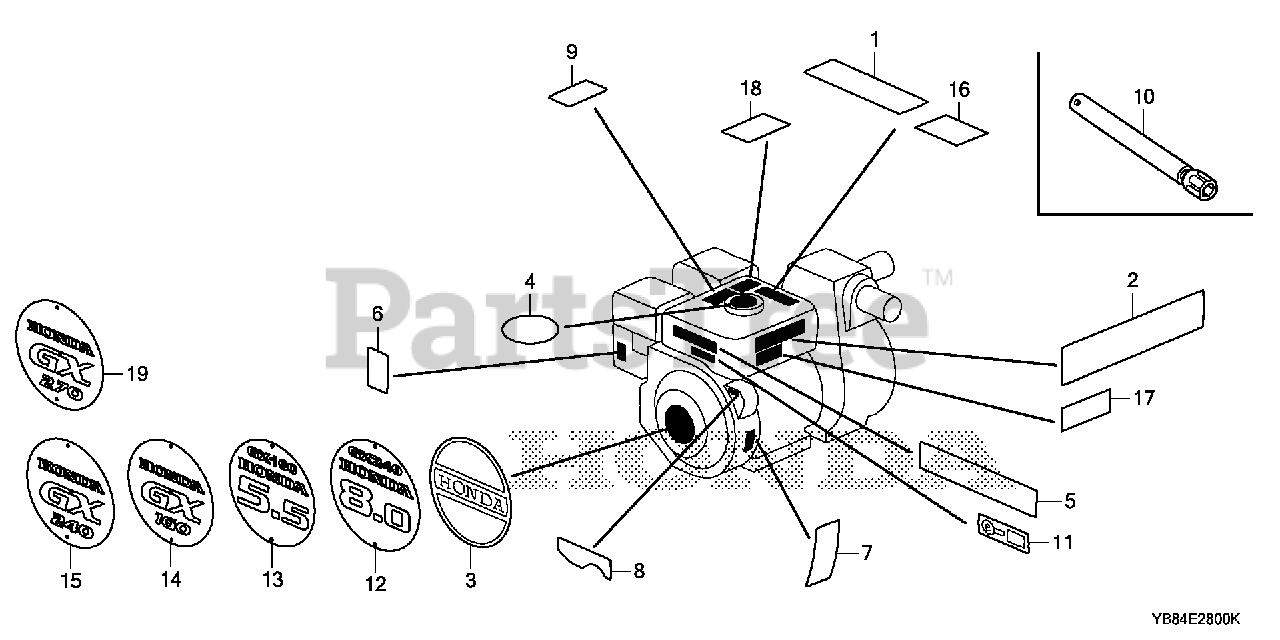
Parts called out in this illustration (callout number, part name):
6	MARK, CHOKE
10	WRENCH, SPARK PLUG
16	LABEL, OPERATOR WARNING (ENGLISH)
17	MARK, OIL ALERT (ENGLISH)
18	MARK, EX. CAUTION (ENGLISH)
19	EMBLEM (GX270)
